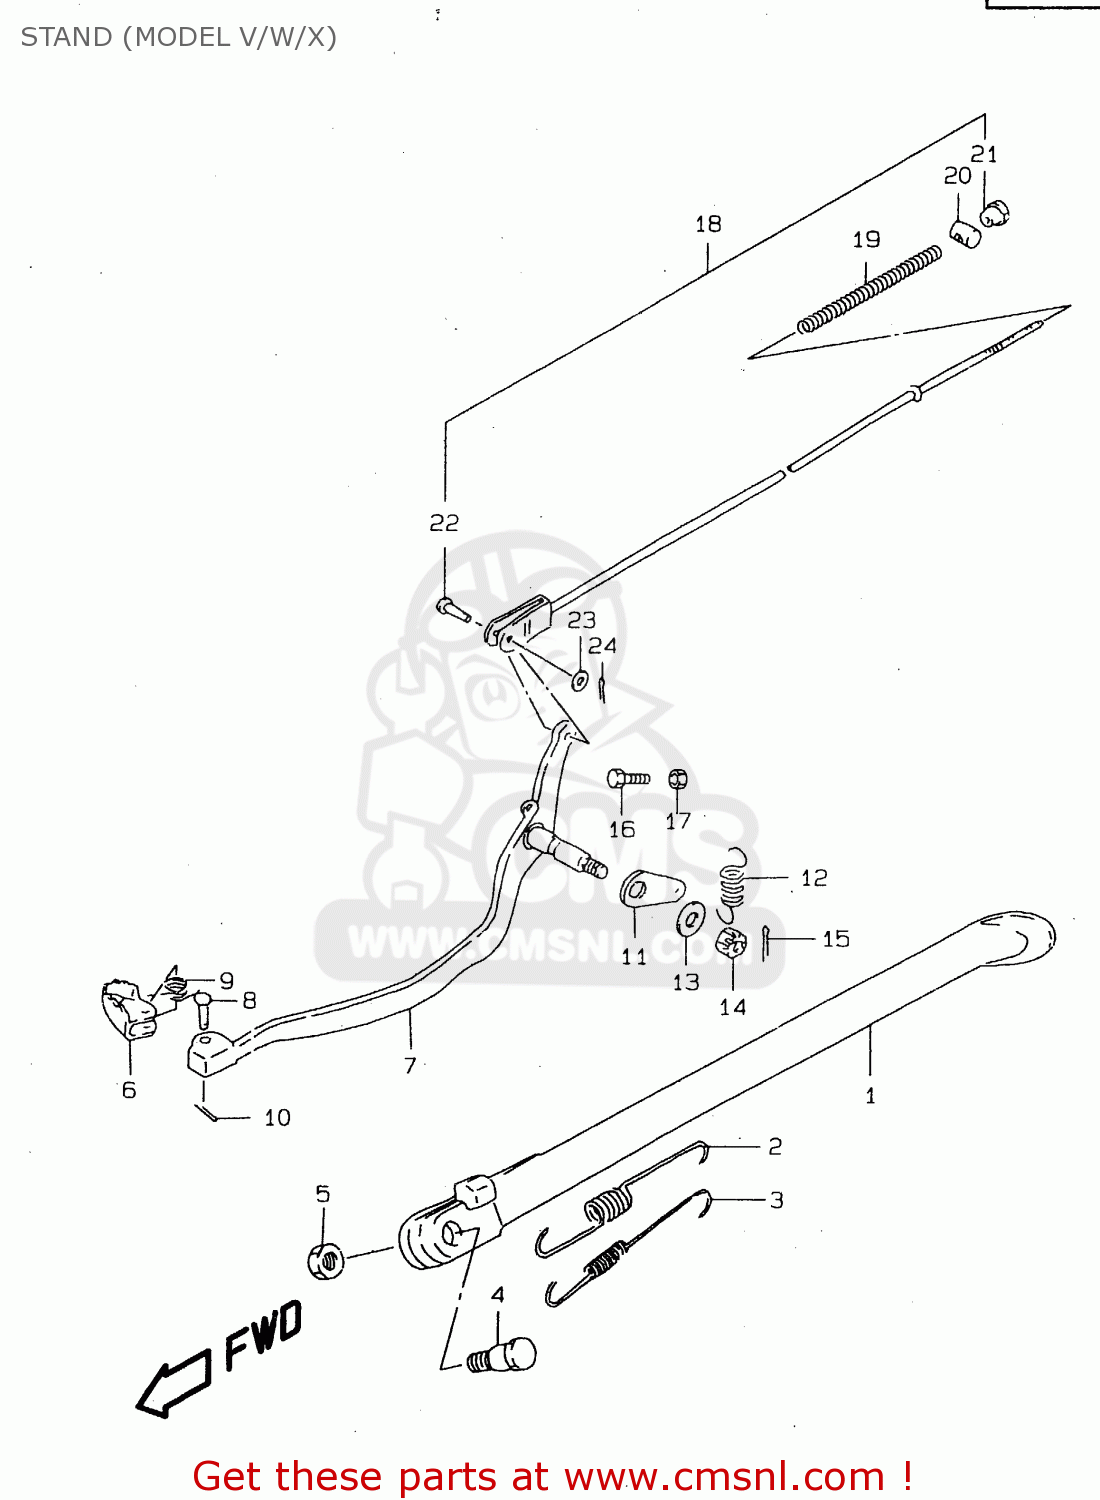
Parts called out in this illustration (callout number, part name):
1	STAND COMP,PROP
2	SPRING
3	SPRING
4	BOLT L:30
5	NUT
6	PEDAL,BRAKE
7	ARM,BRAKE PEDAL
8	PIN
9	SPRING
10	PIN
11	ARM,BRAKE RETURN SPRING
12	SPRING
13	WASHER
14	NUT
15	PIN 20X20
16	BOLT(6X23)
17	NUT 6MM
18	ROD ASSY,RR BRAKE
19	SPRING
20	PIN(13X18)
21	NUT
22	PIN(L:13.5)
23	WASHER
24	PIN 20X20
